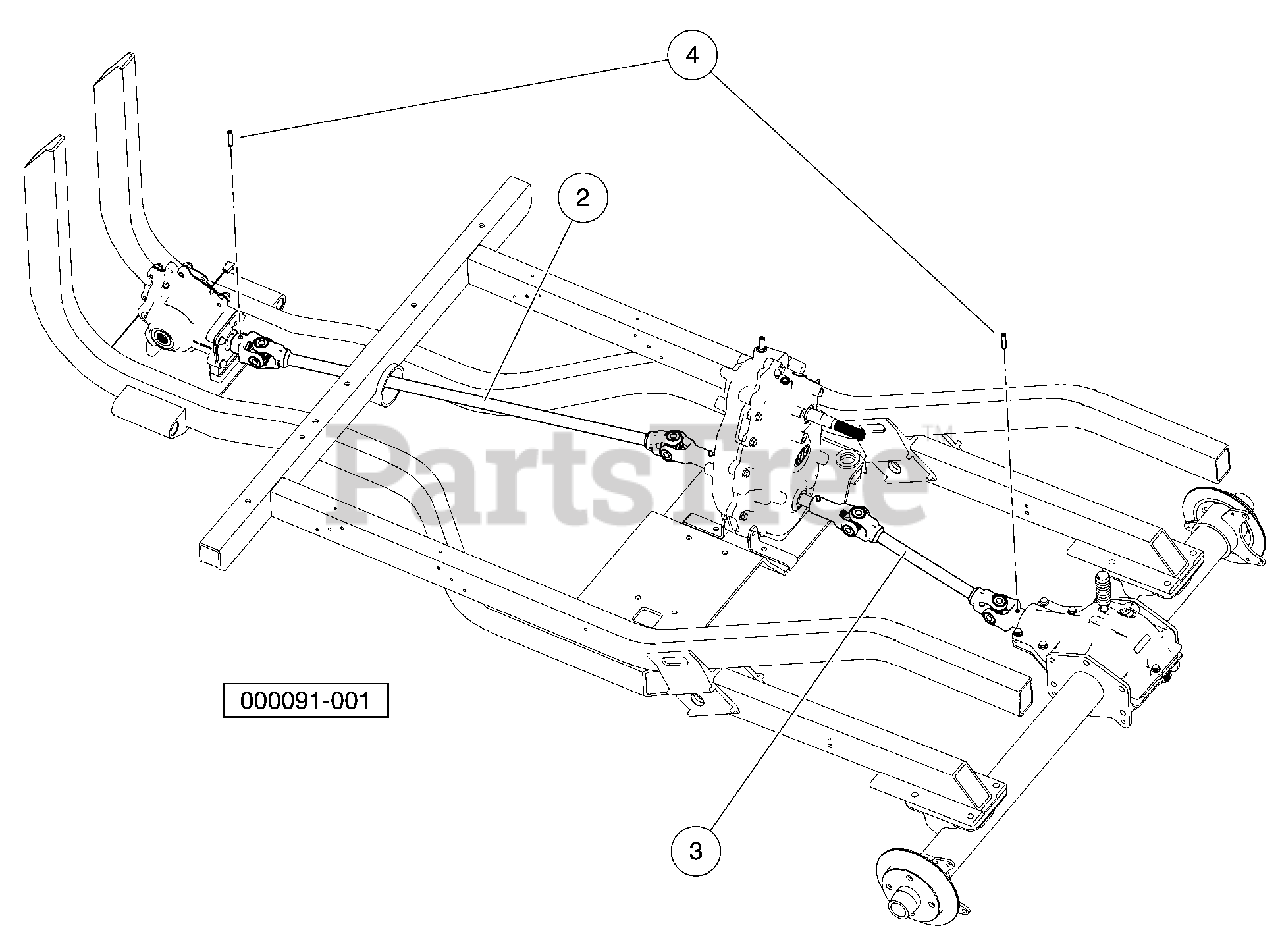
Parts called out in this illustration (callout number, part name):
1	Inst, Prop Shafts, Awd
2	Prop Shaft, Front
3	Prop Shaft, Rear
4	Pin, Spring, 5/16 X 1-1/2 Hd
